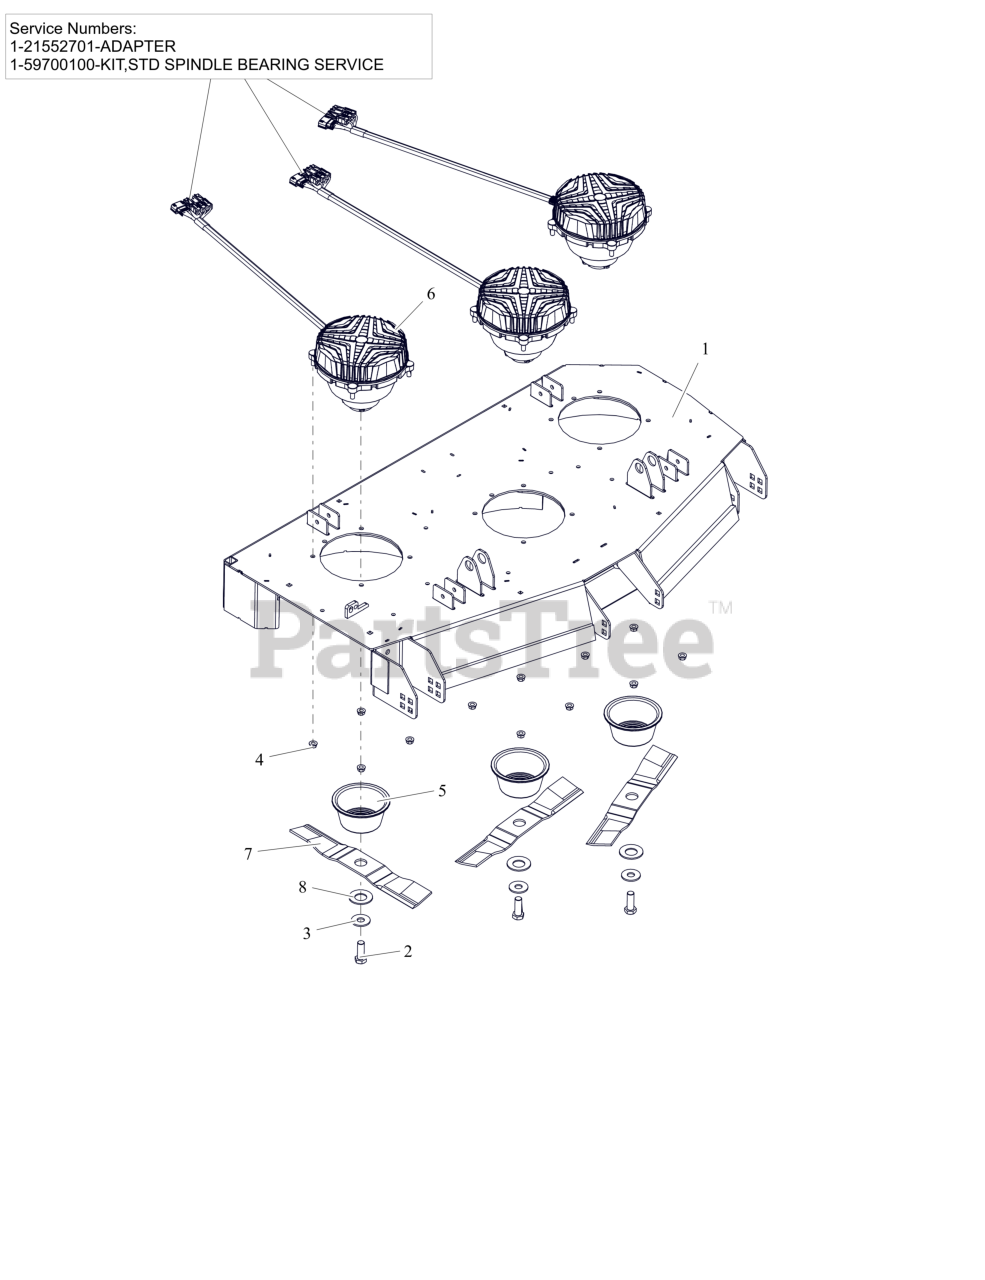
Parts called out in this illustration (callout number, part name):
1	KIT,DECK 48 SD W/DECALS-G
2	BLT, HEX .62-18X1.75 G8 ZCC
3	WSHR, HRDN 0.687X1.75X0.134 HRD
4	NUT-LK-CTR-FLG .375-16 GF ZCC
5	GUARD, SPINDLE LOWER
6	MOTOR, DECK - 48"/52" CW
6	ADAPTER
6	KIT, STD SPINDLE BEARING SERVICE
7	BLADE, MOWER -16.190" EFF CW
8	WSHR, BLVL - .56X28.5X3 PHOS.COAT
